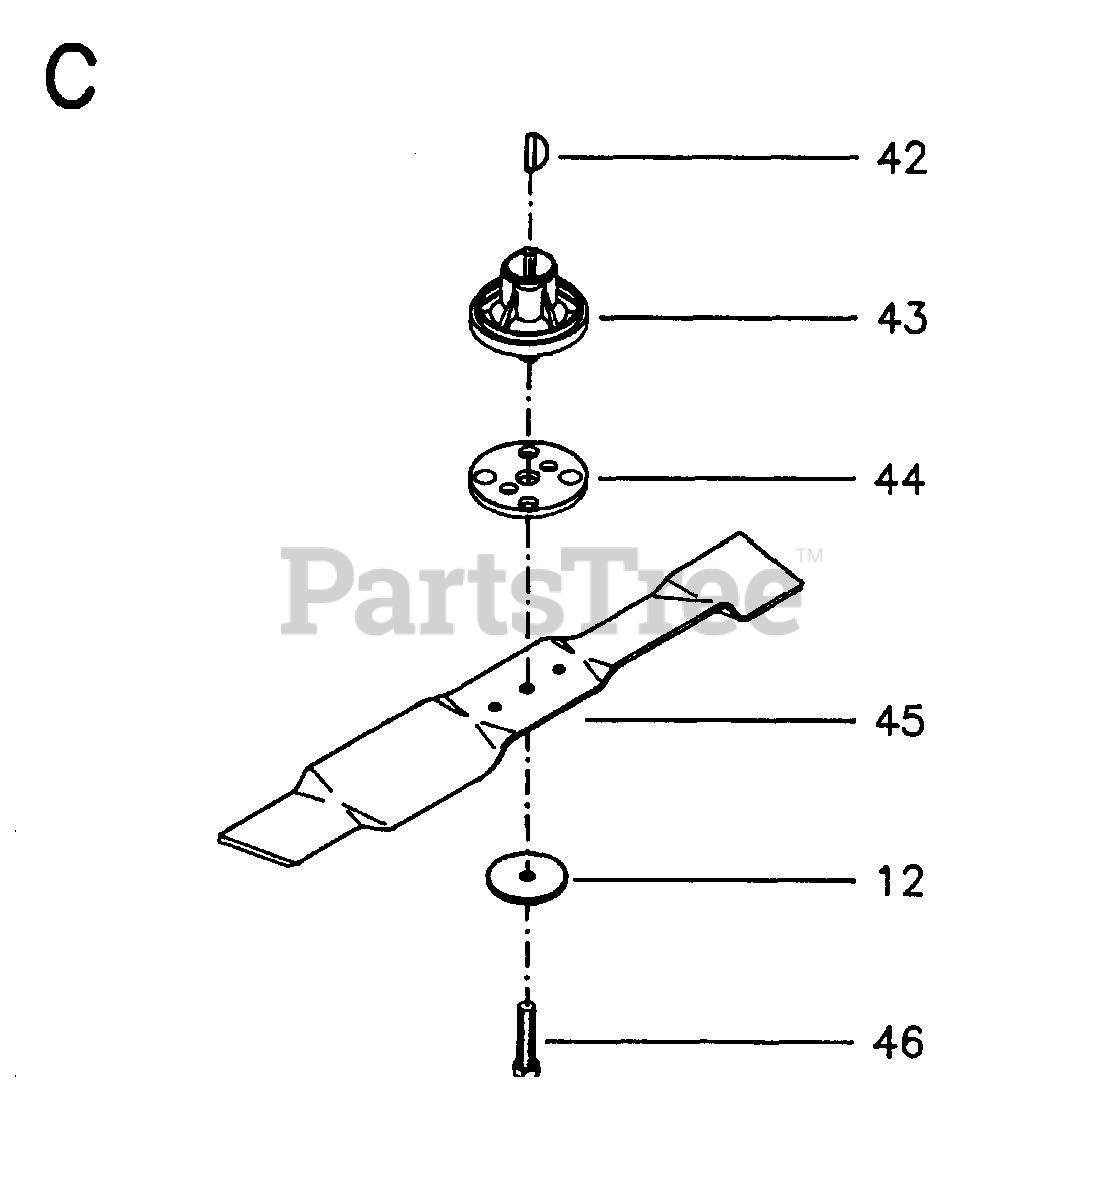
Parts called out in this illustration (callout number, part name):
42	WOODRUFF KEY
43	BLADE ADAPTER
44	STEEL PLATE ADAPTER
45	BLADE
